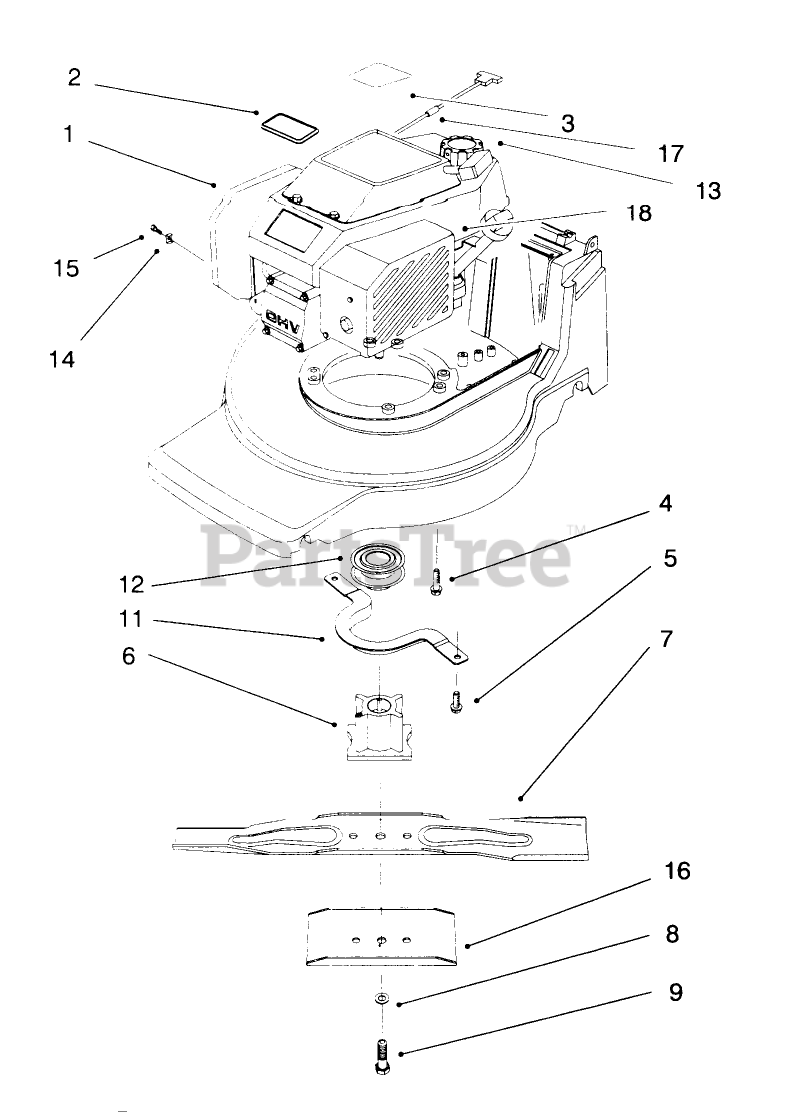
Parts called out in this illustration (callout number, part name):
1	Engine
2	PLATE-LOGO
3	DECAL - ENGINE
4	SCREW-HWH
5	SCREW-HWH
6	BLADE RETAINER - 25 MM
7	Blade
8	WASHER-LOCK
9	BOLT-BLADE
11	Guide-Belt
12	PULLEY-DRIVE, ZONE START
13	CAP-GAS
14	CLAMP-CASING
15	CLAMP SCREW F/W ENGINE
16	Stiffener Blade
17	STOP-ROPE
18	COVER - BRAKE F/W
